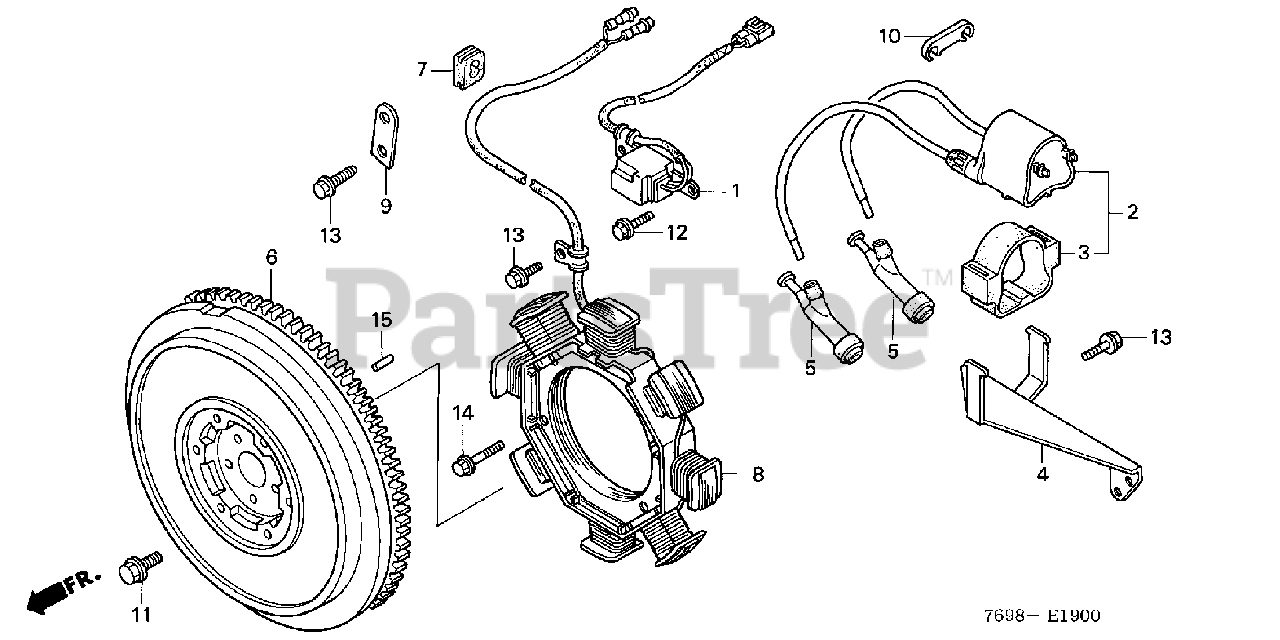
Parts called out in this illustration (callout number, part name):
1	COIL ASSY., PULSER
2	COIL ASSY., IGNITION
3	SUSPENSION, IGNITION COIL
4	BRACKET, IGNITION COIL
5	CAP ASSY., NOISE SUPPRESSOR (NICHIWA Y-EZ RTFM256)
7	GROMMET, WIRE
8	COIL ASSY., CHARGE
9	BRACKET, WIRE HARNESS CLIP
10	CLAMP, WIRE
11	BOLT, HEX. (10MM)
12	BOLT, FLANGE (5X16)
13	BOLT, FLANGE (6X14)
14	BOLT, FLANGE (6X25)
15	PIN B, DOWEL (6X10)
